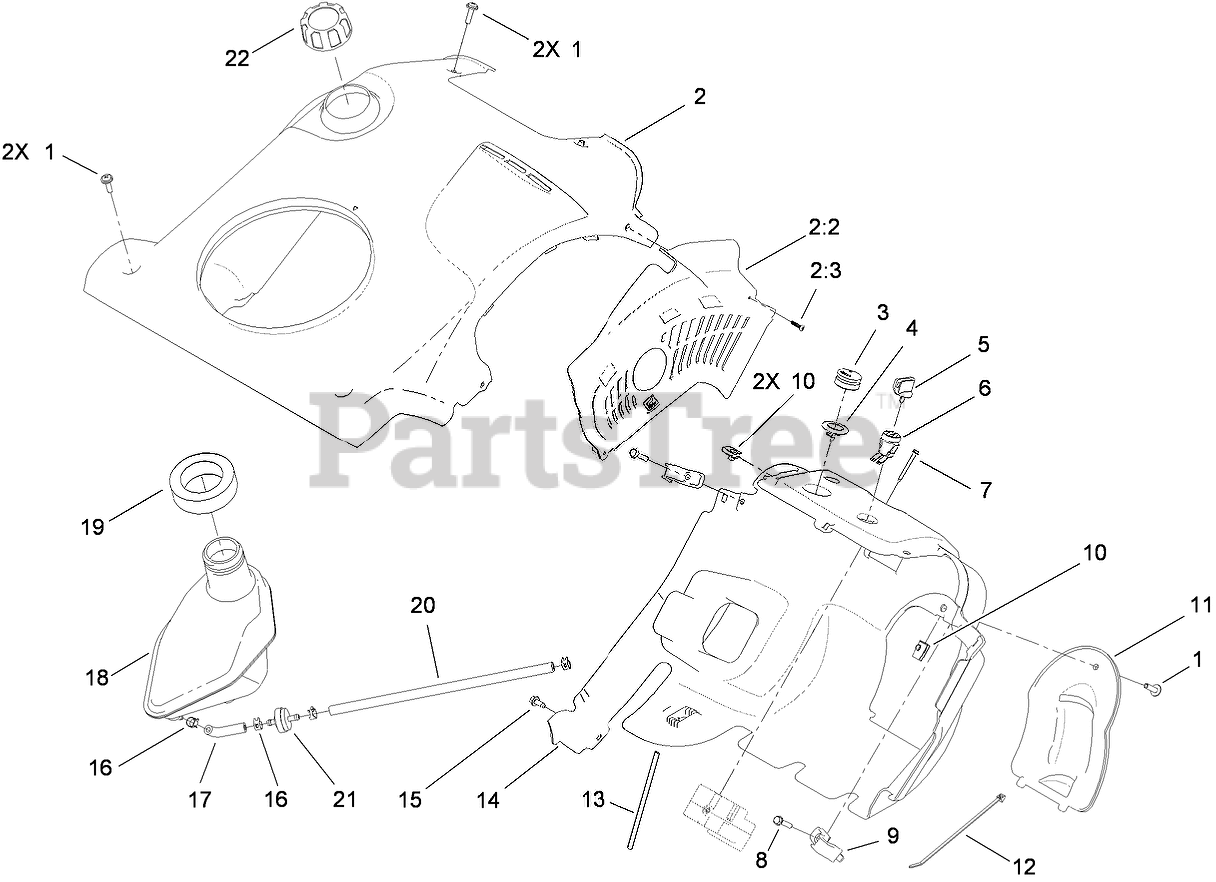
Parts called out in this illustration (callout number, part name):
1	SCREW-PPH
2	SHROUD ASM
2:2	BAFFLE-HEAT
2:3	SCREW-PPH
3	BULB-PRIMER
4	BODY-PRIMER
5	KEY-IGNITION
6	SWITCH
7	SCREW-PLASTITE
8	SCREW-PLASTITE
9	CLIP-SHROUD
11	PANEL-ACCESS, CARBURETOR
12	TIE-CABLE
13	HOSE-PRIMER
14	SHROUD-LOWER
15	SCREW-HWH
16	CLAMP-HOSE
17	HOSE-FUEL
18	TANK-GAS
19	SEAL-TANK
20	HOSE-FUEL
21	FILTER-FUEL
22	GAS CAP ASM
